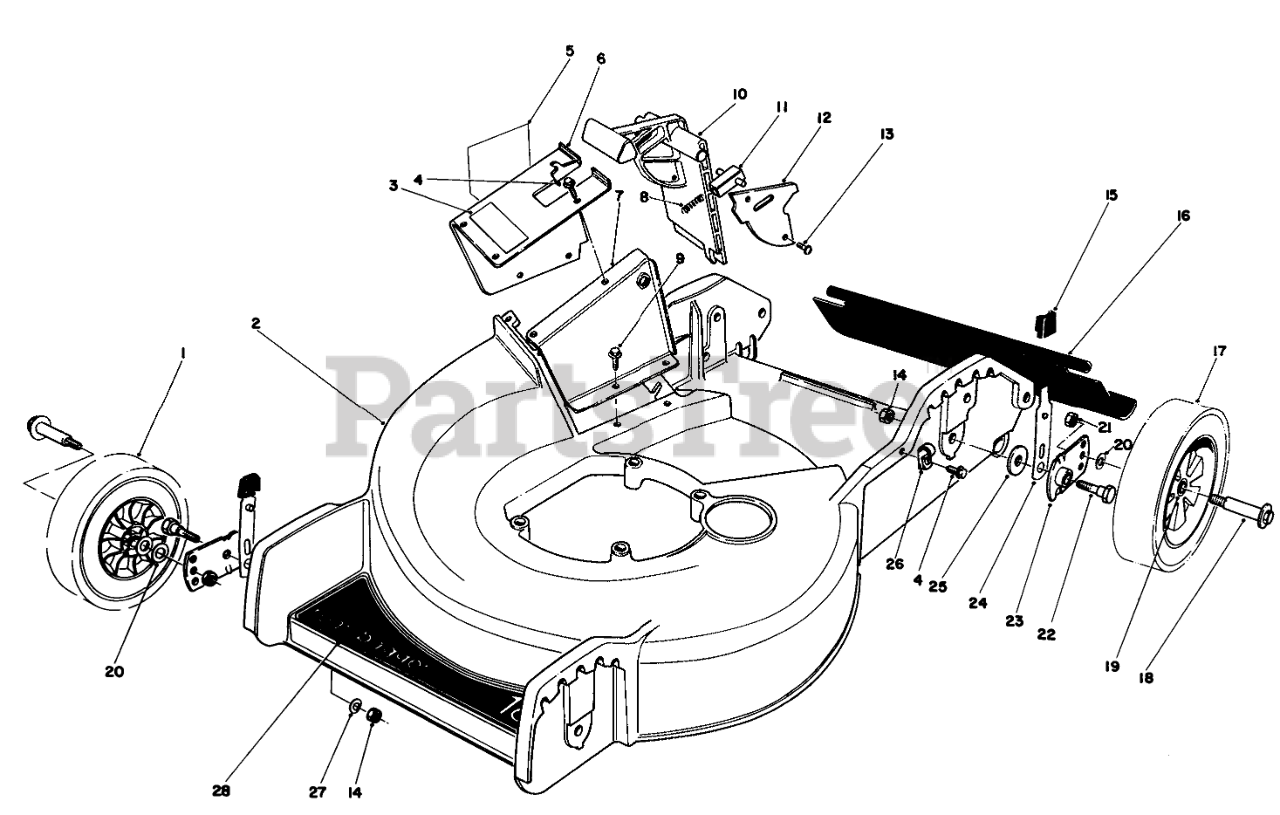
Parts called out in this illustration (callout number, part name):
1	Wheel & Tire Assembly (Incl. Ref. #19)
2	HSG & CARTON
3	Decal-Door
4	SCREW
5	DECAL-DANGER
6	Tunnel-Outer (Incl. Ref. #3 & 5)
7	Tunnel-Inner
8	SPRING-COMPRESSION, LATCH
9	SCREW
10	Door Mulching
11	Door Latch
12	Cover Door
14	NUT-LOCK, NI
15	KNOB-ARM
16	SHIELD - TRAILING
17	Wheel & Tire Assembly (Incl. Ref. #19)
18	BOLT-WHEEL
19	BUSHING
20	WASHER
21	Nut
22	5/16-18 PIVOT SCREW
23	PIVOT ARM ASSY
24	SPRING ARM ASM
25	PIVOT WASHER
26	CLAMP-NYLON
27	WASHER-BELLEVILLE
28	DECAL-DECK
